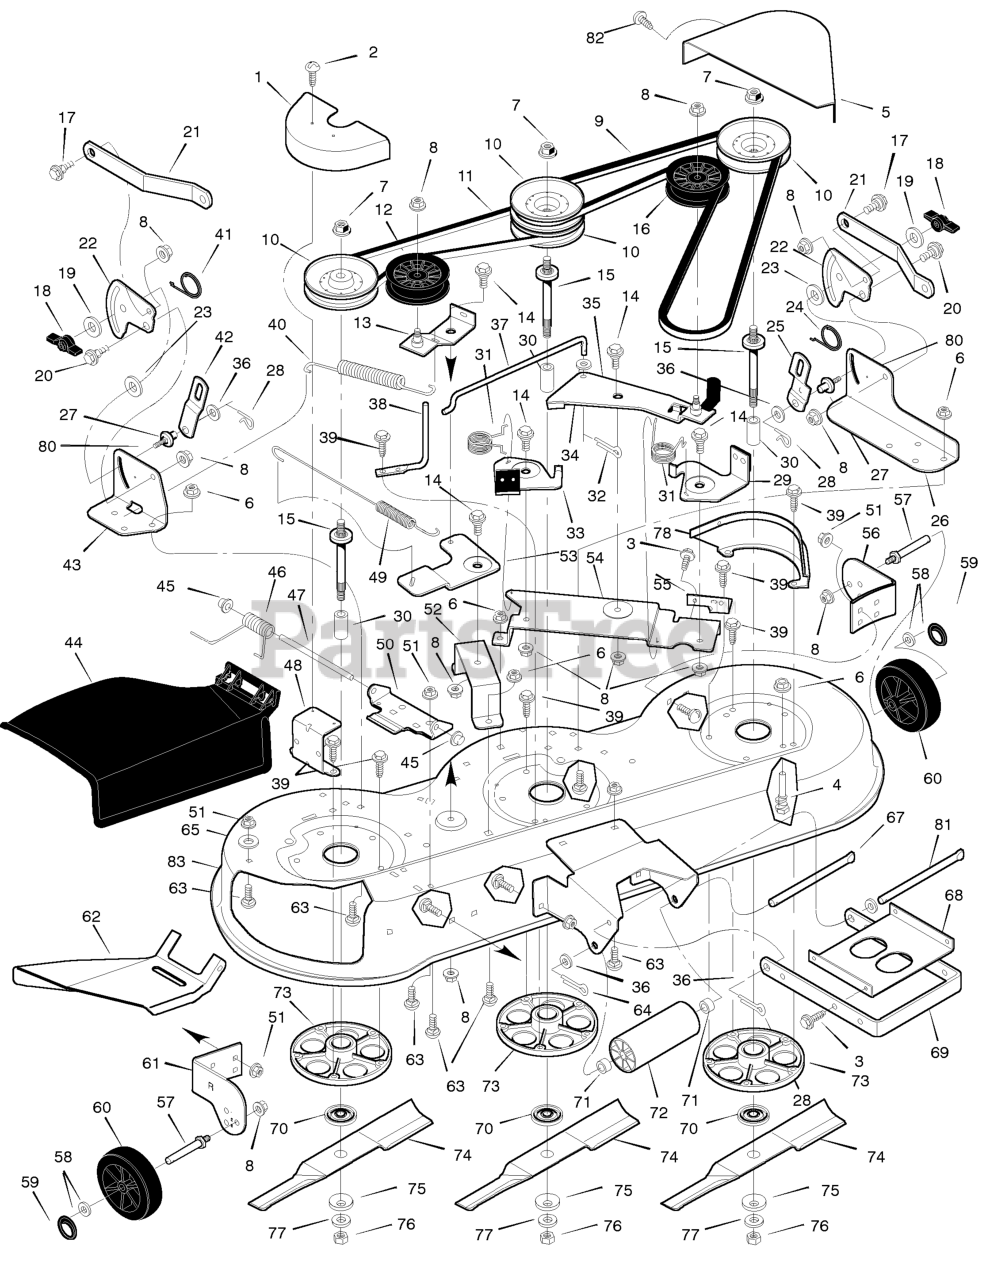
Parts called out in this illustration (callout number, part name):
1	Cover, Right Pulley
2	Screw
4	Guide, Belt
5	Cover, Left Pulley
6	Nut, Hex
7	Nut, Flange
8	Nut, Flange
9	Belt, Primary
10	Pulley
11	Belt, Secondary
12	Pulley, Idler
13	Arm, Idler
14	Bolt, Shoulder
15	Shaft, Splined
16	Pulley, Idler
17	Bolt, Shoulder
18	Knob
20	Bolt, Shoulder
21	Bracket, Rear Suspension
22	Plate, Suspension
23	Pad, Friction
25	Link, Left Lift
26	Bracket, Left Lift
27	Pin, Hanger
28	Pin, Hair
29	Brake Assembly, Left
32	Pin, Cotter
33	Brake Assembly, Right
34	Washer
35	Idler, Arm
37	Link, Bell Crank
38	Guide, Belt
39	Screw
40	Spring, Extension
41	Spring, Torsion
42	Link, Lift
43	Bracket, Right Lift
44	Deflector, Chute
45	Push On Cap
46	Spring, Torsion
47	Rod, Deflector
48	Bracket, Cover
49	Spring, Extension
50	Bracket, Hinge
51	Nut, Flange
52	Bracket, Bell Crank
53	Crank, Bell
54	Plate, Brake Arm
55	Bracket, Brake Plate
56	Bracket, Left Gauge Wheel
57	BOLT, Gauge Wheel
59	Ring, Locking
60	Wheel, Gauge
61	Bracket, Right Gauge Wheel
62	Deflector, Inside
63	Bolt, Carriage
64	Pin, Cotter
66	Bracket, Front Deck
67	Rod, Hanger
68	Stiffener
69	Bracket, Suspension
70	Adapter, Blade
73	Housing, Jackshaft
75	Washer, Belleville
78	Bracket, Pulley Cover
81	Rod, Hanger
83	Housing, Blade
